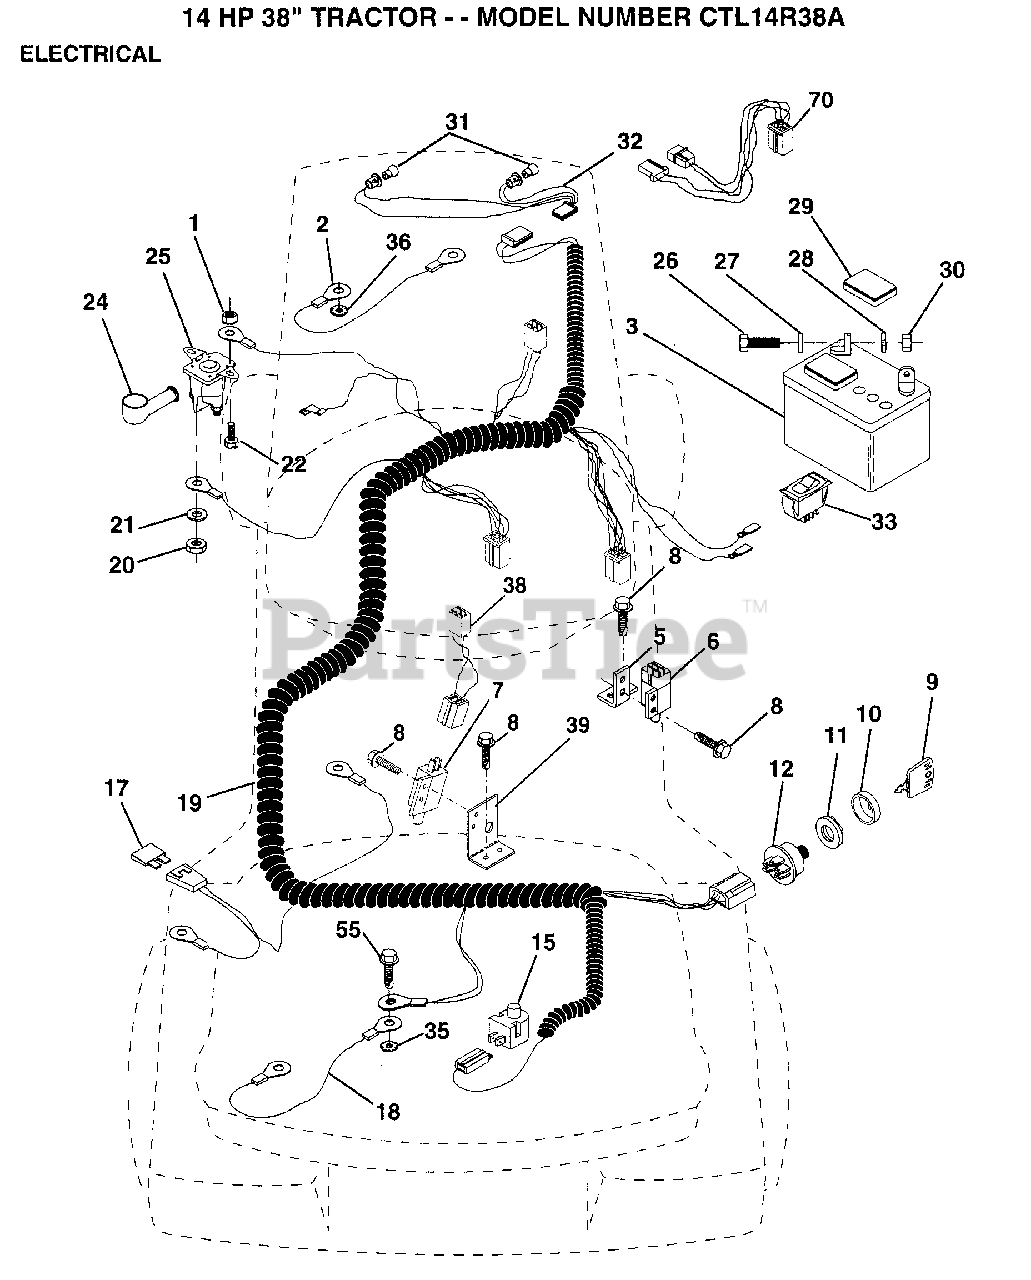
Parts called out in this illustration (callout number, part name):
1	NUT
2	CABLE ASM.
5	BRACKET LT
6	SWITCH INTERLOCKT
7	SWITCH-INTER. GT
8	SCREW
9	KEY MLD GEN DELTA
10	COVER KEY SWITCH
14	WIRE TIE
15	SWITCH SEAT
17	FUSE HYT
18	CABLE ASSY
19	HARNESS.IGN.FEND.
20	NUT
22	BOLT
26	BOLT LT
27	WASHER
28	LOCKWASHER
29	"CAP,BATTERY "
31	HEADLAMP BULB
32	"HARNESS,LIGHT SOC"
33	SWITCH LT
35	LOCKWASHER.5/16.E
36	LOCKWASHER
39	BRACKET SWT CLUTC
55	SCREW LT
70	HARNESS.ENG.DUAL
